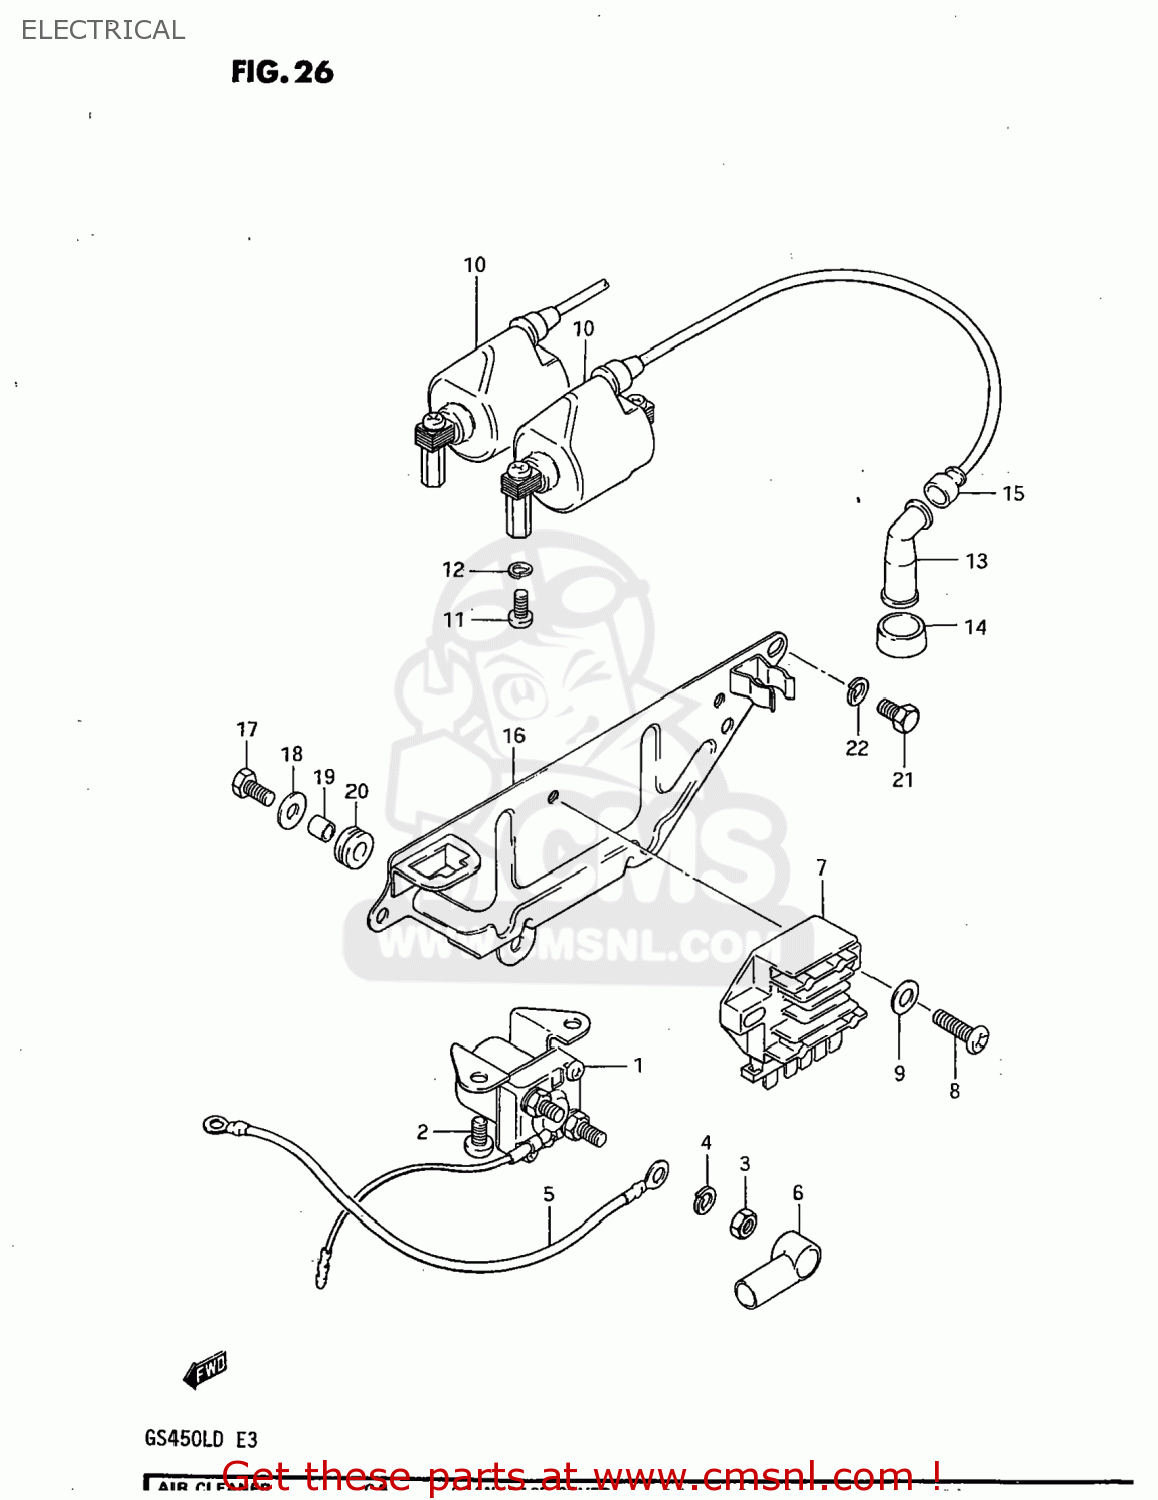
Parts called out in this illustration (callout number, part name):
1	RELAY ASSY,STARTING MOTOR
2	SCREW
3	NUT 6MM
4	LOCK WASHER
5	CORD,BATTERY MINUS
6	CAP,STARTER RELAY
7	RECTIFIER ASSEMBLY
8	SCREW
9	WASHER
10	COIL ASSEMBLY,IGNITION
11	SCREW
12	LOCK WASHER
13	CAP,SPARK PLUG
14	SEAL,SPARK PLUG
15	SEAL,SPARK PLU
16	HOLDER COMP,ELECTRONIC PARTS
17	BOLT
18	WASHER
19	SPACER (6.1X8X9.5)
20	CUSHION
21	BOLT
22	LOCK WASHER
